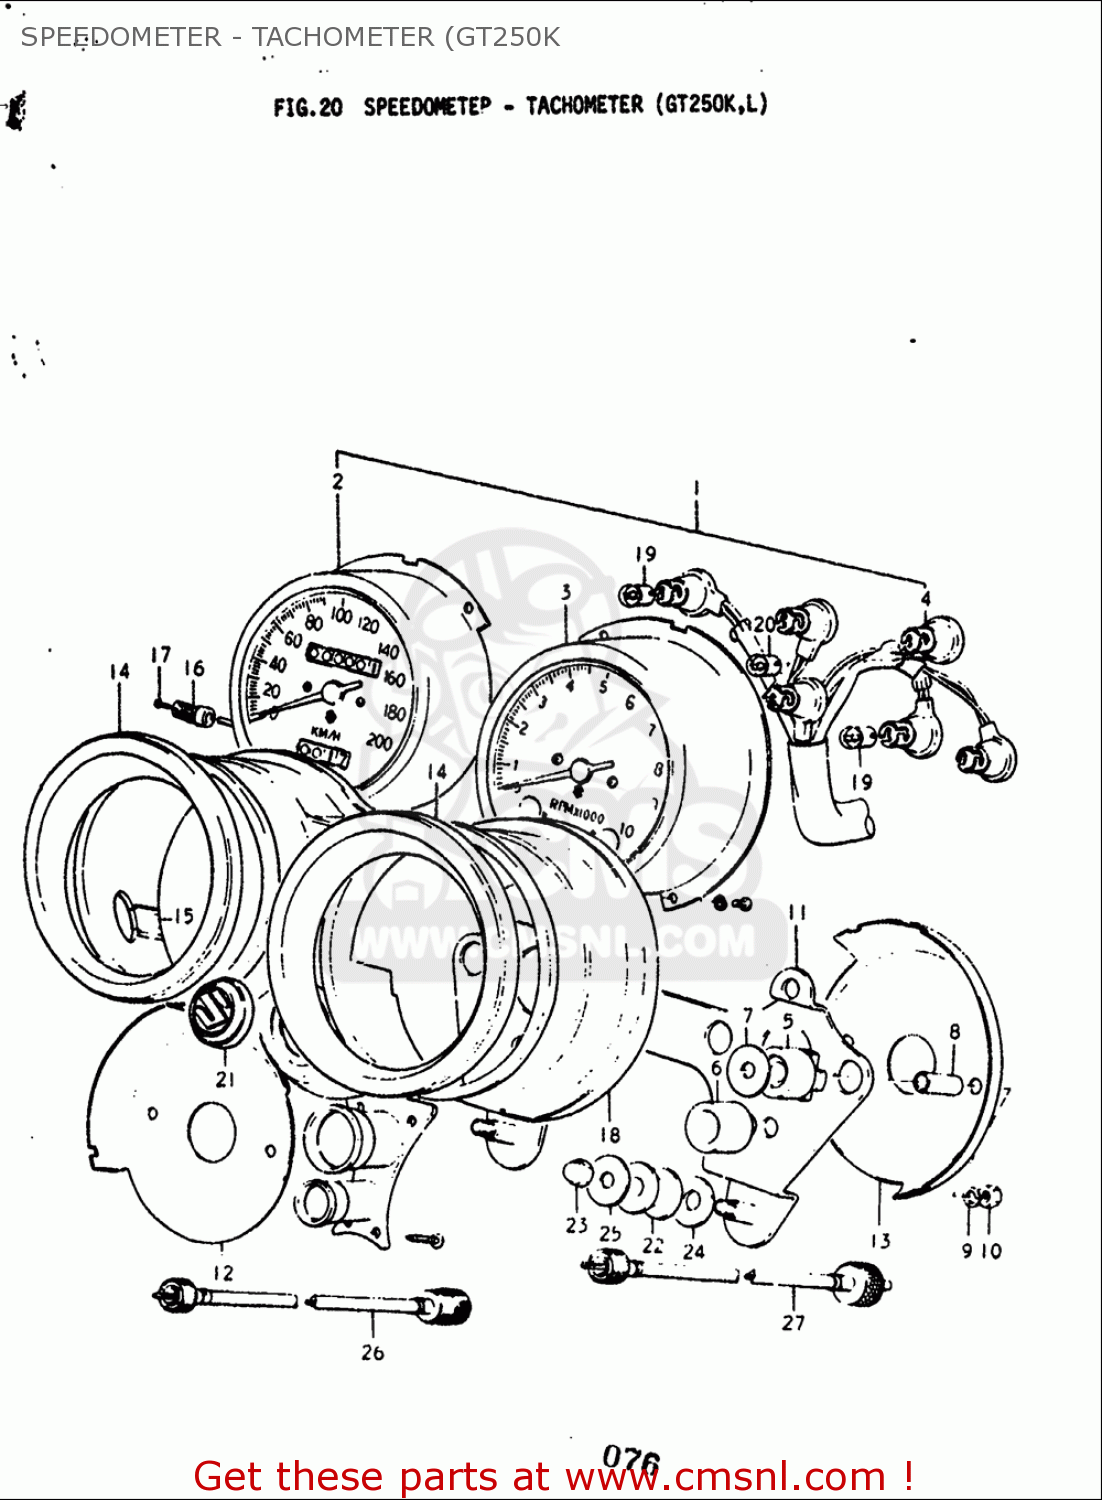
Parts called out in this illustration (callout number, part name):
1	SPEEDOMETER ASSY
5	CUSHION,METER NO.1
6	CUSHION,METER
9	WASHER,LOCK
10	NUT
14	VISOR
15	CAP
16	KNOB, TRIP METER
17	SCREW(2X6)
19	BULB(12V3.4W,STANLEY,A72A)
20	BULB(12V1.7W,A71A)
21	CAP,SPEED WARNER LAMP HOLE
22	CUSHION
23	NUT
24	WASHER
25	WASHER(6.5X18X1.6)
26	CABLE ASSY,SPEEDOMETER
27	CABLE ASSY,TACHOMETER
